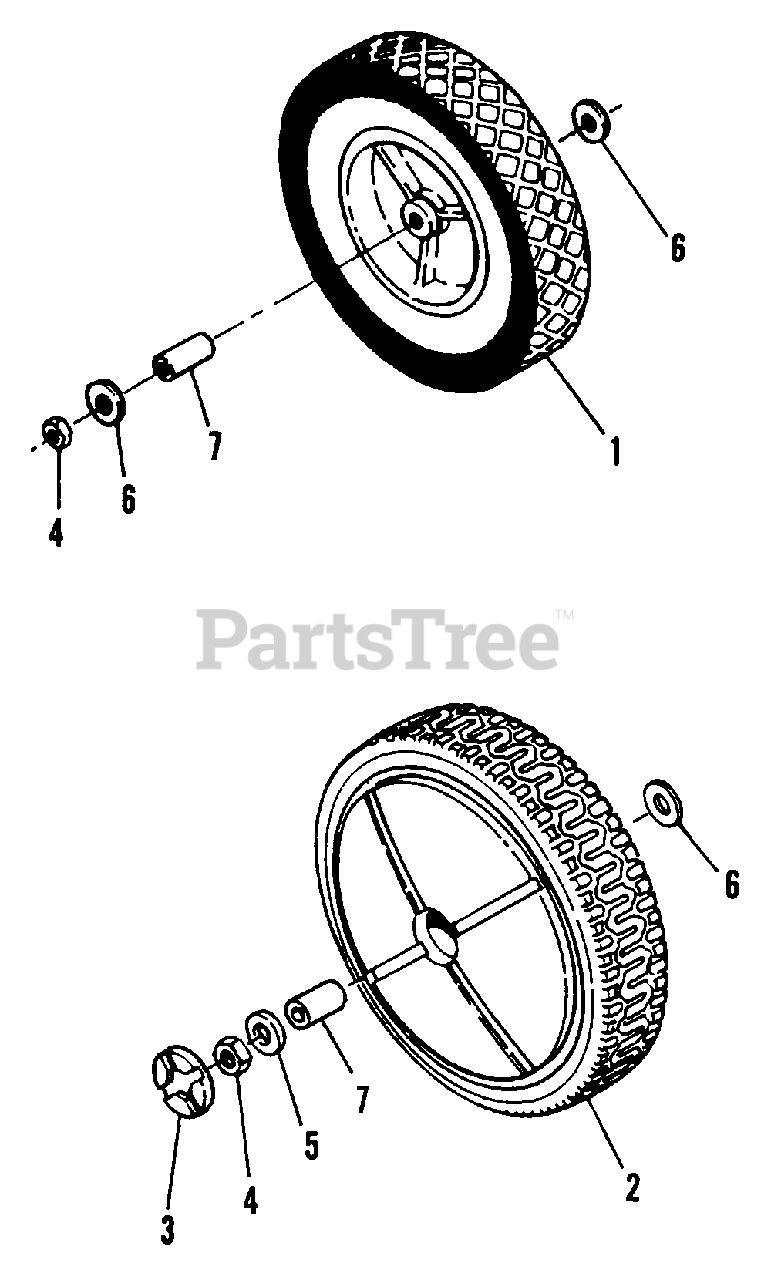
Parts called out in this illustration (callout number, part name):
1	WHEEL, 7 x 1.50 Plastic
2	WHEEL, 8 x 2.00 Plastic
3	PLUG, Wheel
4	NUT, 7/16-20 Hex (Thin)
5	WASHER, 7/16 x 7/8" O.D. Flat
6	WASHER, 7/16 x 1" O.D. Flat
7	BUSHING, Axle
